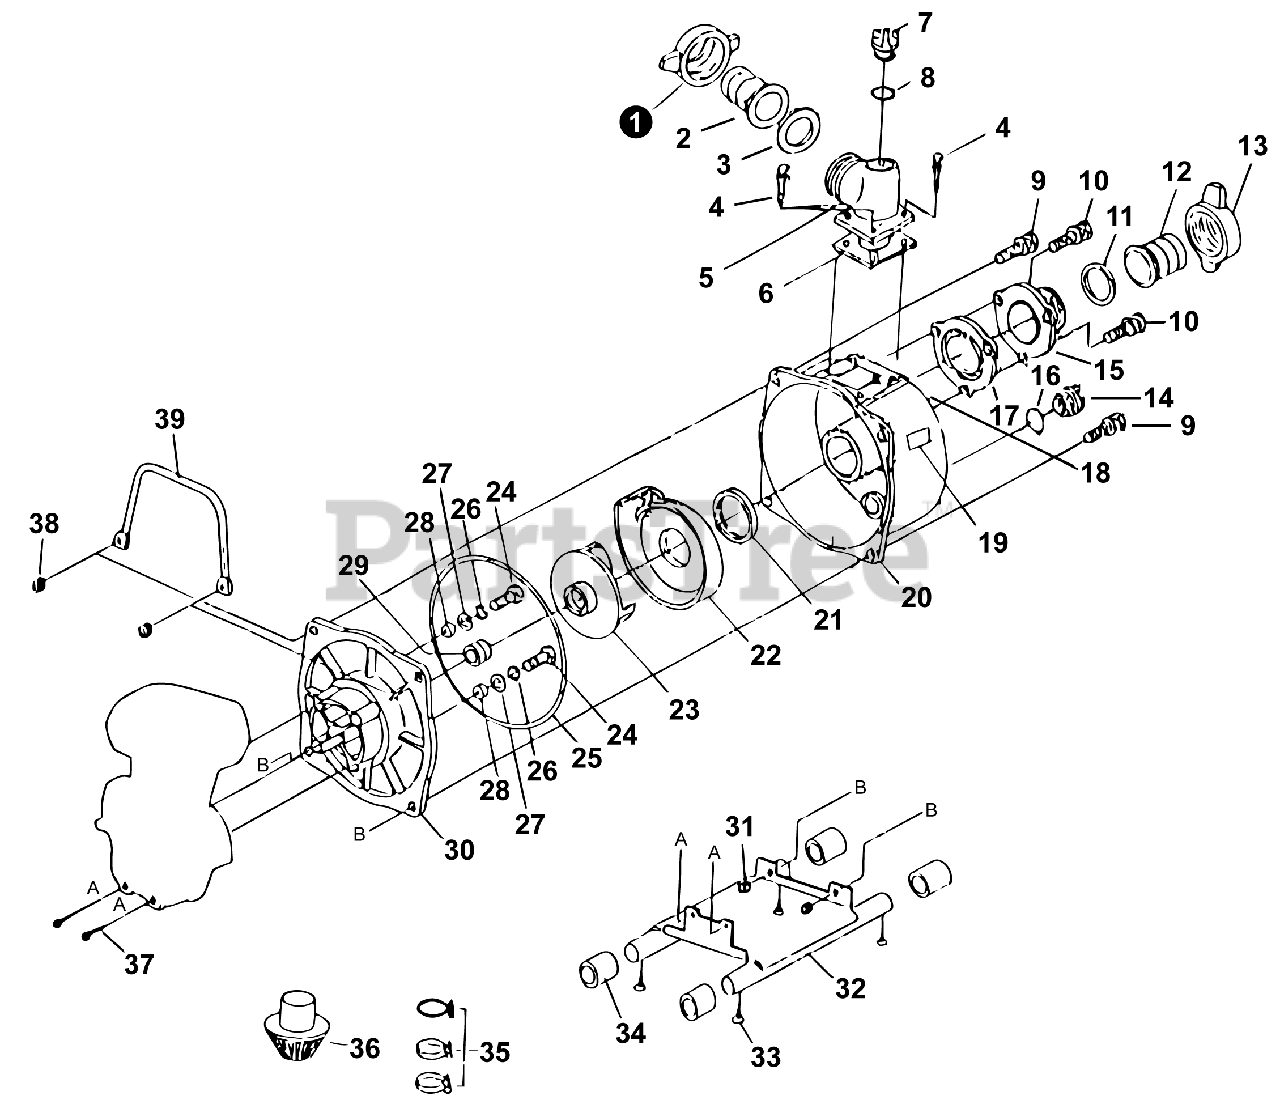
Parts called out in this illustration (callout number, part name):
1	NUT, RING
2	COUPLING, HOSE
3	GASKET
4	BOLT, TAPPING
5	ELBOW
6	GASKET
7	PLUG
8	O-RING
9	BOLT
10	BOLT, TAPPING
11	GASKET
12	COUPLING, HOSE
13	NUT, RING
14	PLUG
15	COVER, DISCHARGE
16	O-RING
17	VALVE, INTAKE
18	LABEL, CAUTION
19	LABEL, SPEC
20	HOUSING, PUMP
21	PACKING
24	BOLT
25	PACKING
26	WASHER, SPRING
27	WASHER
29	SEAL, MECHANICAL
30	COVER, PUMP
31	NUT, FLANGE
32	BASE, PUMP
33	SCREW, TAPPING
34	CUSHION
35	CLAMP, HOSE
36	STRAINER
37	BOLT
38	NUT
39	HANDLE
